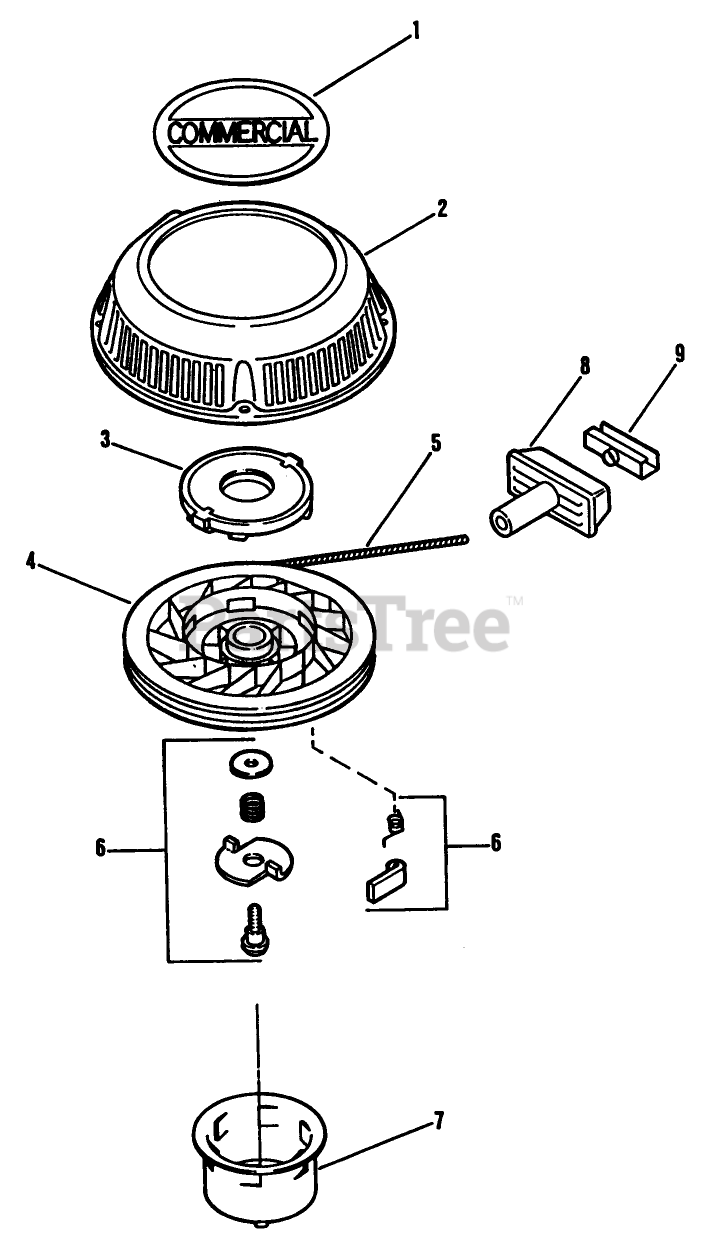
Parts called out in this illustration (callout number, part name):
4	PULLEY
6	DOG KIT
7	HUB-STARTER E COMM.
9	CLIP-STARTER
